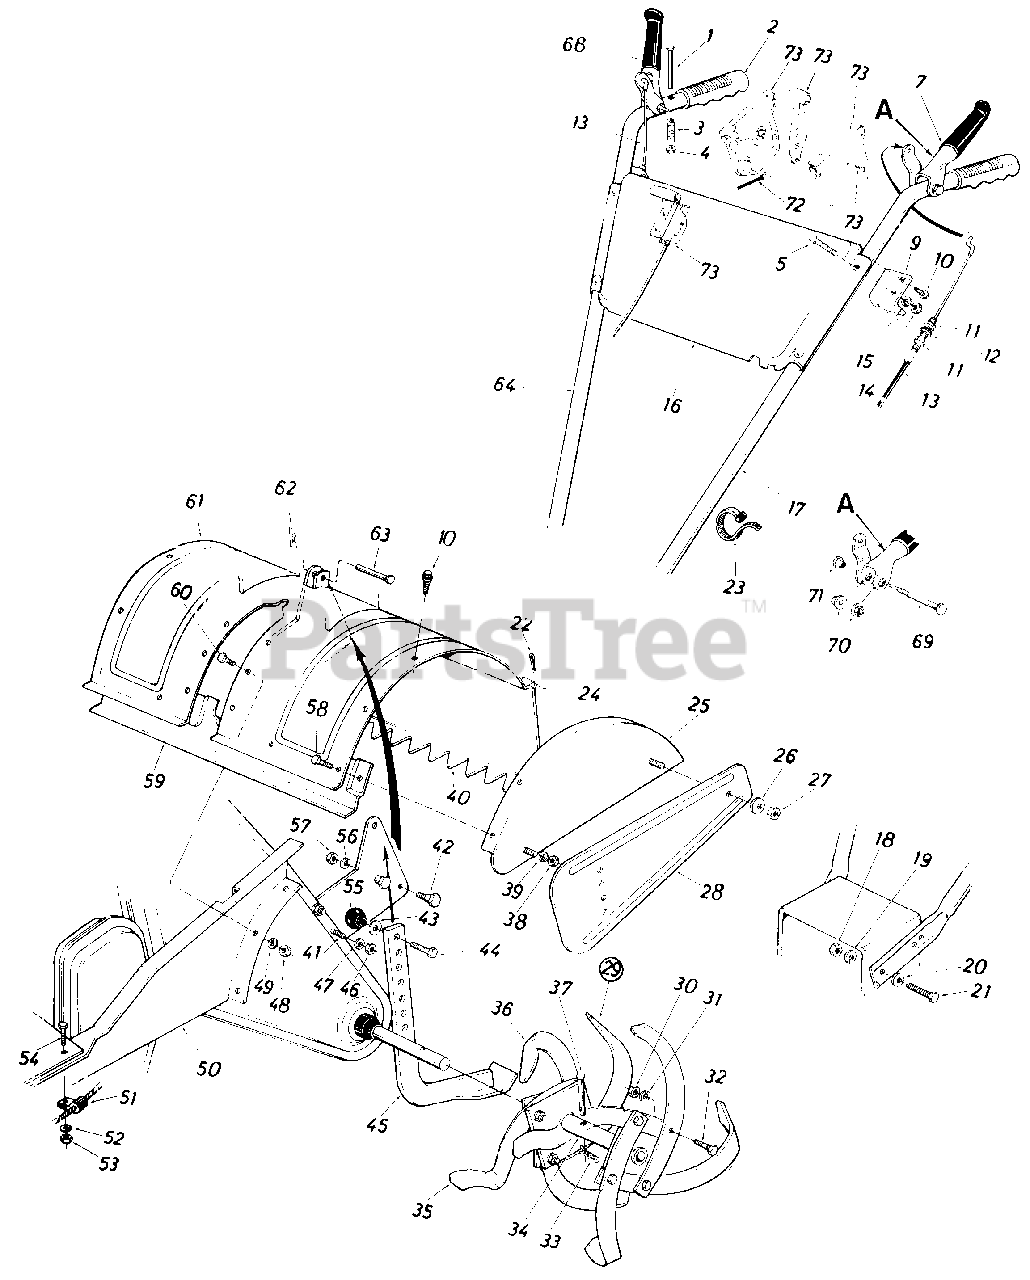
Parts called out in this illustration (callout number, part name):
1	Clevis Pin 1/4" Dia. x 2.25" Lg.
2	Grip
3	Compression Spring .33" O.D. x 1.2" Lg.
4	Cap Speed Nut 1/4" Rod
5	Carr. Bolt 5/16-18 x 1.75" Lg.
7	Clutch Grip Ass'y. - L.H. (Tines)
9	Clutch Cable Bracket
10	Hex Wash. S-Tap Scr. 5/16-18 x .62" Lg.
11	Hex Nut 5/16-18 Thd.
12	L-Wash. 5/16" I.D.
13	Clutch Control Cable
14	Hex Nut 5/16-18 Thd.
15	L-Wash. 5/16" I.D.
16	Handle Panel
17	Handle - L.H.
18	Hex Nut 3/8-16 Thd.
19	L-Wash. 3/8" I.D.
20	Bell-Wash. 3/8" I.D.
21	Hex Bolt 3/8-16 x 1.00" Lg.
22	Cotter Pin 3/32" Dia. x 3/4" Lg.
23	Cable Tie
24	Tiller Flap Rod
27	Hex Nut 5/16-18 Thd.
31	L-Wash. 3/8" I.D.
32	Hex Bolt 3/8-24 x 1.25" Lg.
33	Hairpin Cotter
38	Hex Nut 5/16-18 Thd.
39	L-Wash. 5/16" I.D.
41	Hex Bolt 5/16-18 x 5/8" Lg.
42	Shld. Bolt 1/2" Dia. x .426" Lg.
43	Fl-Wash. 3/8" I.D. x 5/8" O.D. x .03
44	Hex Bolt 3/8-16 x 3/4" Lg.
46	Hex Nut 5/16-18 Thd.
47	L-Wash. 5/16" I.D.
48	Hex Nut 5/16-18 Thd.
49	L-Wash. 5/16" I.D.
52	L-Wash. 5/16" I.D.
53	Hex Nut 5/16-38 Thd.
54	Hex Bolt 5/16-18 x 3/4" Lg.
55	Ball Knob 1 1/4" Dia. x 3/8-16 Thd.
56	L-Wash. 3/8" I.D.
57	Hex Nut 3/8-16 Thd.
58	Hex Bolt 5/16-18 x .75" Lg.
61	Tine Shield Ass'y.
62	Hairpin Cotter
63	Clevis Pin 3/8" Dia.
69	Shoulder Bolt .38" Dia. x 1.53" Lg.
70	Hex Flange Plastic Bearing
71	Shoulder Nut 1/4-20 Thd.
72	Throttle Control Wire
73	Throttle Control Box Ass'y.
